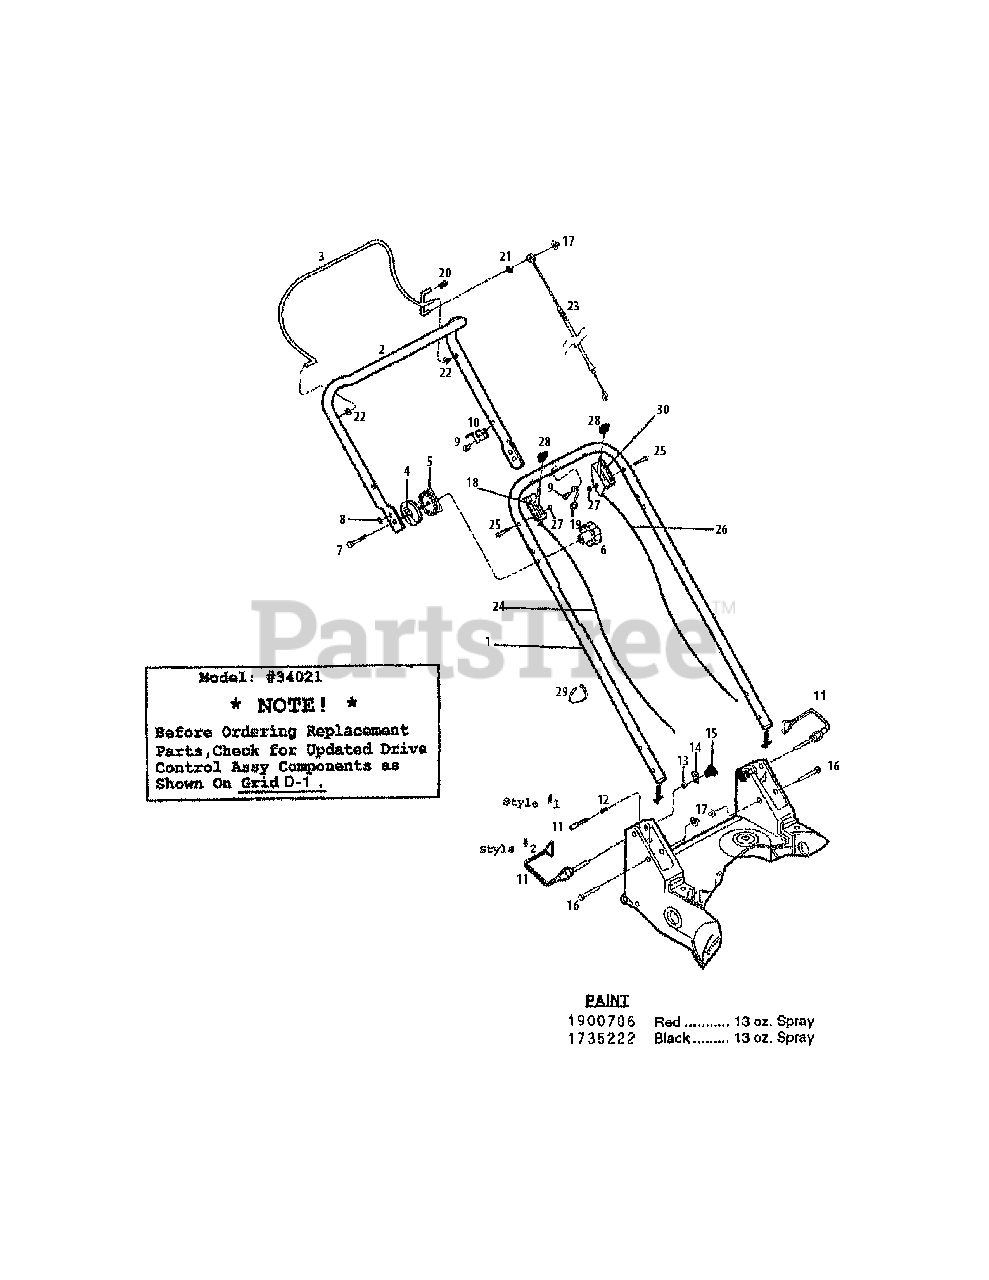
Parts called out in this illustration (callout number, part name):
1	HANDLEBAR-LOWER
2	HANDLEBAR-UPR PNT
3	BAIL-CONTROL VINYL COATED
4	QUADRANT-OUTER (WAS 1767425)
5	KIT-QUADRANT INNER (WAS 1767375)
6	KNOB-HANDLE ADJUST
7	SCR-CURVED HD 5/16-18X2.0 (WAS 1767448)
8	RETAINER .25
9	SCR-FLANGE 1/4-20X3/4 GR5
10	BRKT-CONTROL CABLE
11	PIN-LK SQ. #W51620LP
11	PIN-STOP
12	SPRING-COMPRESSION
13	NUT-HEX 1/4-20 ZP
14	ARM-STOP ZP BLACK CHRMATE
16	PIN-CLEVIS ( @DEPL)
17	CAP-PUSH .312
18	DECAL-ENGINE SPEED
19	GUIDE-ROPE
20	CAP PLASTIC (BAIL)
21	GRIP-RING EXT .312 ID
22	BUSHING-PLASTIC (BAIL)
23	CABLE-ENGINE BRAKE
24	CONTROL-THROTTLE
25	SCR-HH 1/4-20X1.75 G5 ZP {34020, 34021}
26	CONTROL-CLUTCH {34021}
27	NUT-HT LK 1/4-20 {34020, 34021}
28	KNOB-WHEEL DRIVE CABLE {34020, 34021}
29	TIE-CABLE {34020, 34021} REUSABLE
30	DECAL-WHEEL DRIVE {34021}
